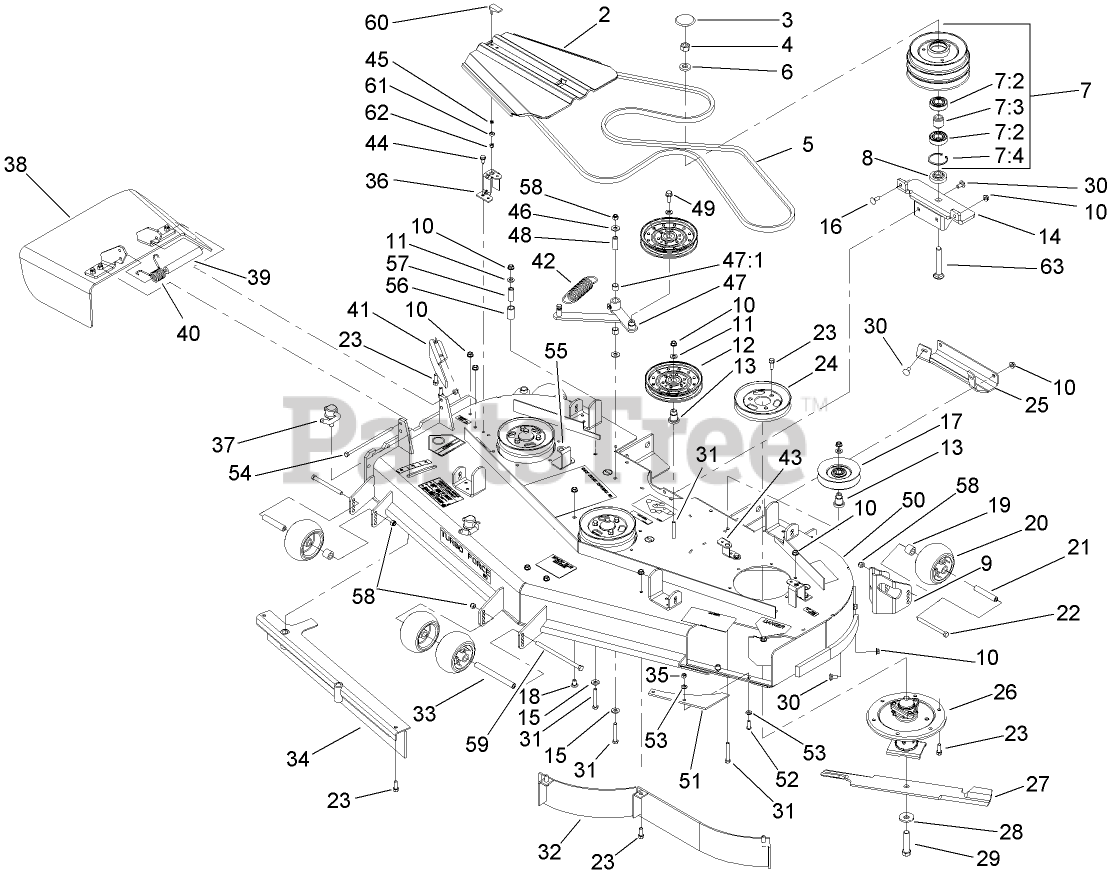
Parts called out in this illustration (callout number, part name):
2	COVER-BELT
3	CAP-PLASTIC
4	NUT-HEX
5	BELT-V
6	SPACER
7	PULLEY AND BEARING ASM
7:2	BEARING-BALL
7:3	SPACER-BEARING
7:4	RING-SNAP
8	SPACER-FLANGED
9	MOUNT-WHEEL, LH
10	NUT-HHF, WHIZ
11	WASHER-FLAT
12	Idler-Flat
13	MOUNT-PULLEY
14	MOUNTING BRACKET ASM
15	WASHER-BELLEVILLE
16	BOLT-CARR
17	PULLEY-IDLER
18	SCREW-CARR
19	TUBE-SPACER
20	ROLLER-SCALP, ANTI
21	TUBE-SPANNER
22	SCREW-HH
23	SCREW-HWH
24	Pulley
25	Plate-Skid
26	SPINDLE ASM
27	BLADE-HI FLOW
28	Washer-Blade Bolt, Heavy
29	Screw-Cap
30	SCREW-CARR
31	SCREW-HH
33	SPACER-WHEEL
35	NUT-LOCK, NI
36	BRACKET-COVER
37	LEVER ASM
38	RUBBER DEFLECTOR ASM
39	SPACER
40	SPRING-TORSION
41	BAFFLE-DISCHARGE
42	SPRING-EXTENSION
43	BRACKET-COVER, TALL
44	SCREW-HWHTF
45	WASHER
46	WASHER-FLAT
47	IDLER ARM ASM
47:1	SLEEVE-BEARING
48	BUSHING
49	SCREW-HHF
50	DECK DECAL ASM
51	PLATE-TURBO
52	SCREW-HSBH
53	WASHER-SPRING
54	SCREW-HH
55	BRACKET-COVER
56	SPACER-RUBBER
57	SPACER-PIVOT, IDLER
58	NUT-LOCK, NI
59	SCREW-HH
60	HANDLE-LATCH, SWELL
61	BUSHING-LATCH, SWELL
62	NUT-LOCK, HH
63	BOLT-CARRIAGE
